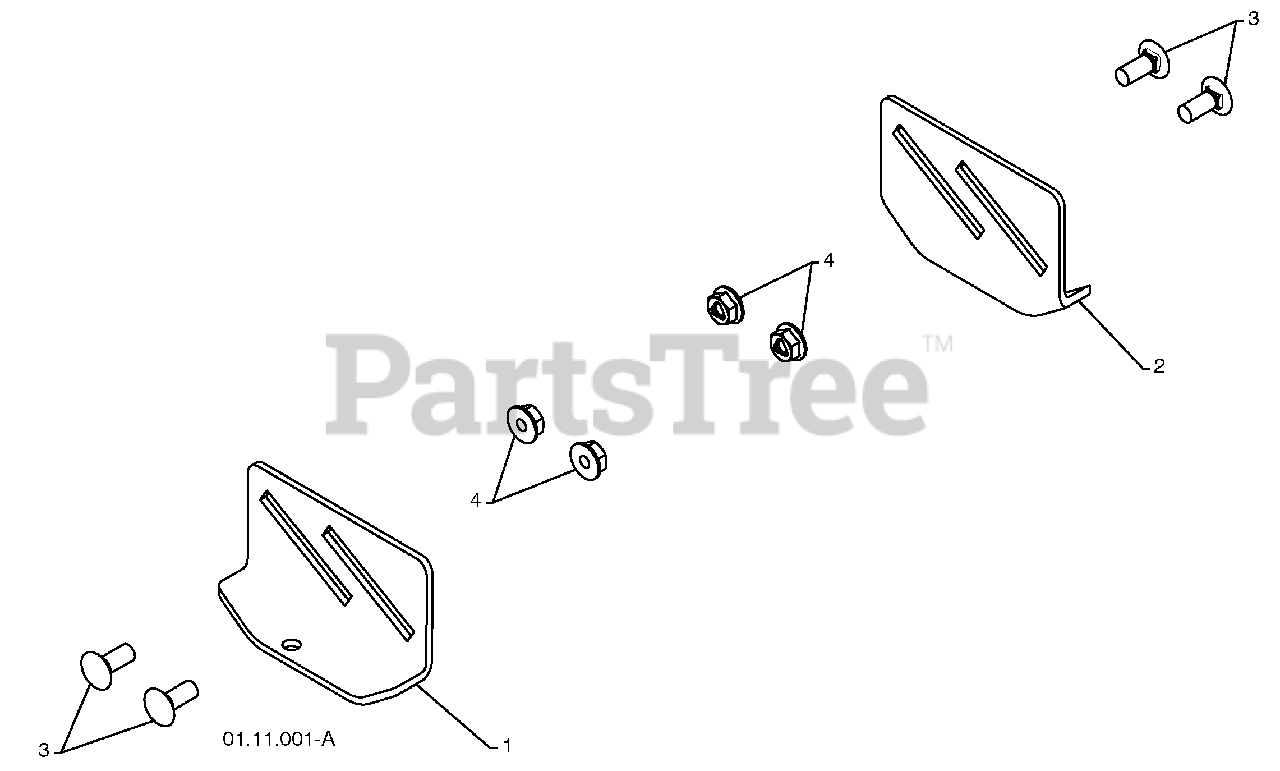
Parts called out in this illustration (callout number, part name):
1	SKID PLATE LH
2	SKID PLATE RH
3	CARRIAGE BOLT 5/16-18 X .75
4	NUT 5/16-18
